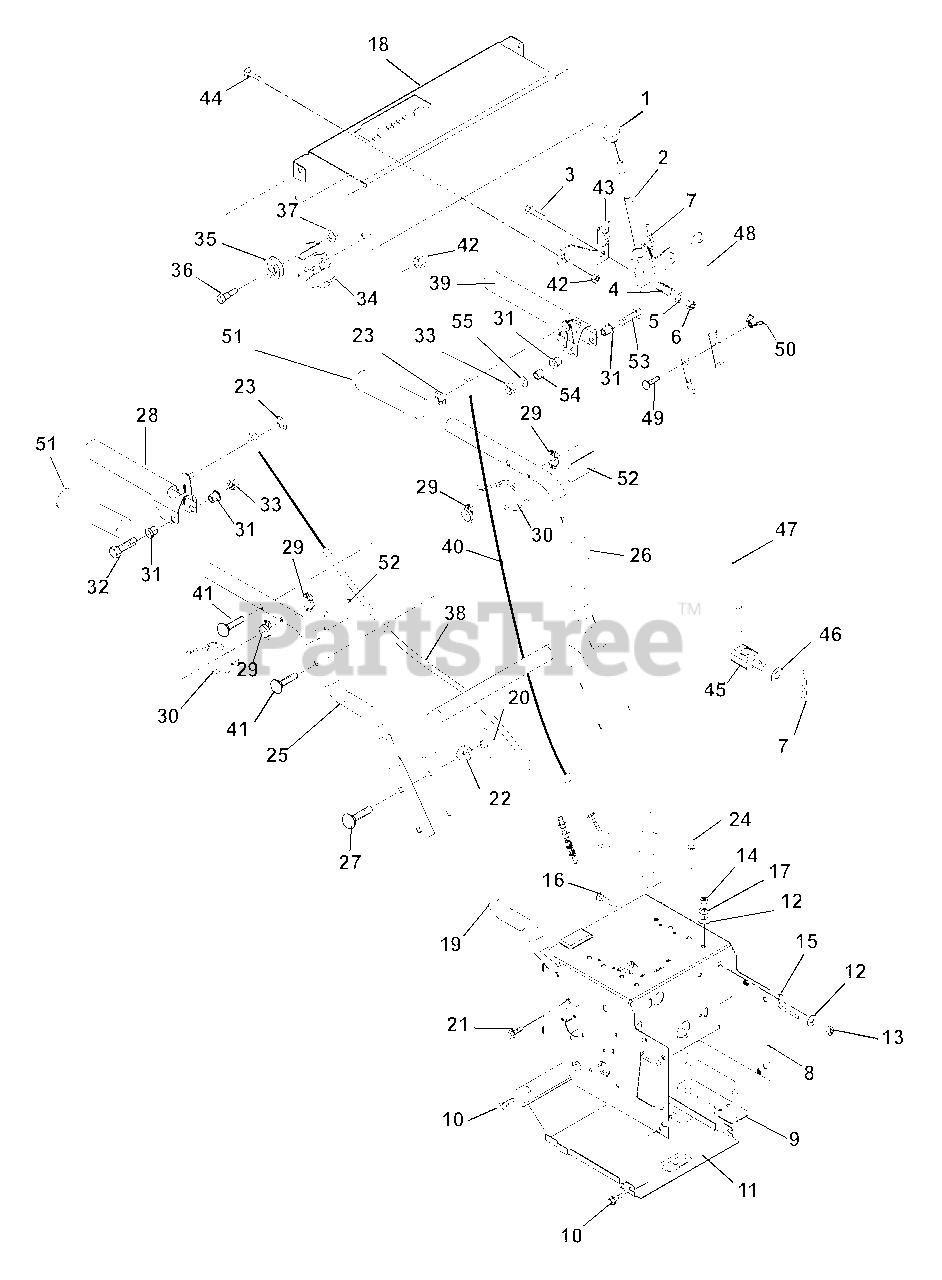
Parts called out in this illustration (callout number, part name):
1	KNOB,BALL -BLACK 1.47" .375-16
2	WMT, SHIFT LEVER
3	@BLT-HEX .38-16X2.00 GR5 YWZC
4	SG-COMP .125X.781X1.250
5	@WSHR-FL-STL.438X1.00X.083 YWZ
6	@NUT-LK-CTR .38-16 YWZC
7	PIN-HAIR INT .08X.18X1.18 YWZC
8	WELDMENT, FRAME - COMPACT SNOW
9	STRAP, ENGINE BOLT-WELDMENT
10	@SCR-TAP .25-20X.37 HWH YWZ TR
11	COVER BOTTOM
12	@WSHR-FL-STL.38X.875X.083 YWZC
13	@NUT-LK-CTR .31-18 YWZC
14	@NUT-HEX .31-18 YWZC
15	BELT FINGER LOWER
16	@BLT-RHDSSQNK .31-18X.75 G5YZ
17	WSHR-LK .312X.097 HVY YWZC
18	CONTROL PANEL W/DECAL
19	HANDLEBAR, LOWER - COMPACT
20	KNOB - WING .312-18 UNC
21	BLT-SERHFWH .38-16X.75 YWZC
22	SPACER, HANDLEBAR
23	RG-RTNG-EXT .250X.010
24	RVT-POP .187X.45 DOME ALUM
25	HANDLEBAR, UPPER - RH COMPACT
26	HANDLEBAR, UPPER - LH COMPACT
27	@BLT-RDHDSQNK .31-18X2.25 G5YZ
28	PADDLE, CLUTCH - RH COMPACT
29	SPACER, HANDLEBAR
30	SPRING, TORSION
31	BSHG, FLG .266X.42X.150 PM
32	@BLT-HEX .25-20X2.50 GR5 YWZC
33	NUT-JAM-NYL .250-20 W/INSERTYZ
34	BRACKET, CABLE MOUNT
35	PULLEY, CABLE
36	BOLT, SHLDR-.375X.375X.25-20
37	@NUT-LK-CTR .25-20 YWZC
38	CABLE, AUGER
39	PADDLE, CLUTCH - LH COMPACT
40	CABLE, TRACTION
41	BLT-RDHDXLSQNK .31-18X1.5 G5YZ
42	@NUT-LK-TOP-FLG .31-18 YWZC
43	BRACKET, SHIFT MOUNT
44	@BLT-RHDSSQNK .31-18X.62 G5YZ
45	PIVOT,SHIFT ROD .375-16(TRUNN)
46	@WSHR-FL-STL.281X.62X.065 YWZC
47	ROD, SHIFT - LOWER
48	ROD, SHIFT - UPPER
49	@BLT-RDHDSQNK .25-20X.75 G5YZ
50	NUT-LK WING .250-20 YWZC
51	HANDLE GRIP
52	BUMPER PAD
53	@BLT-HEX .25-20X3.25 YWZC
54	BSHG, SLV .266 X .750 X .750
55	@WSHR-FL-STL.281X.62X.065 YWZC
